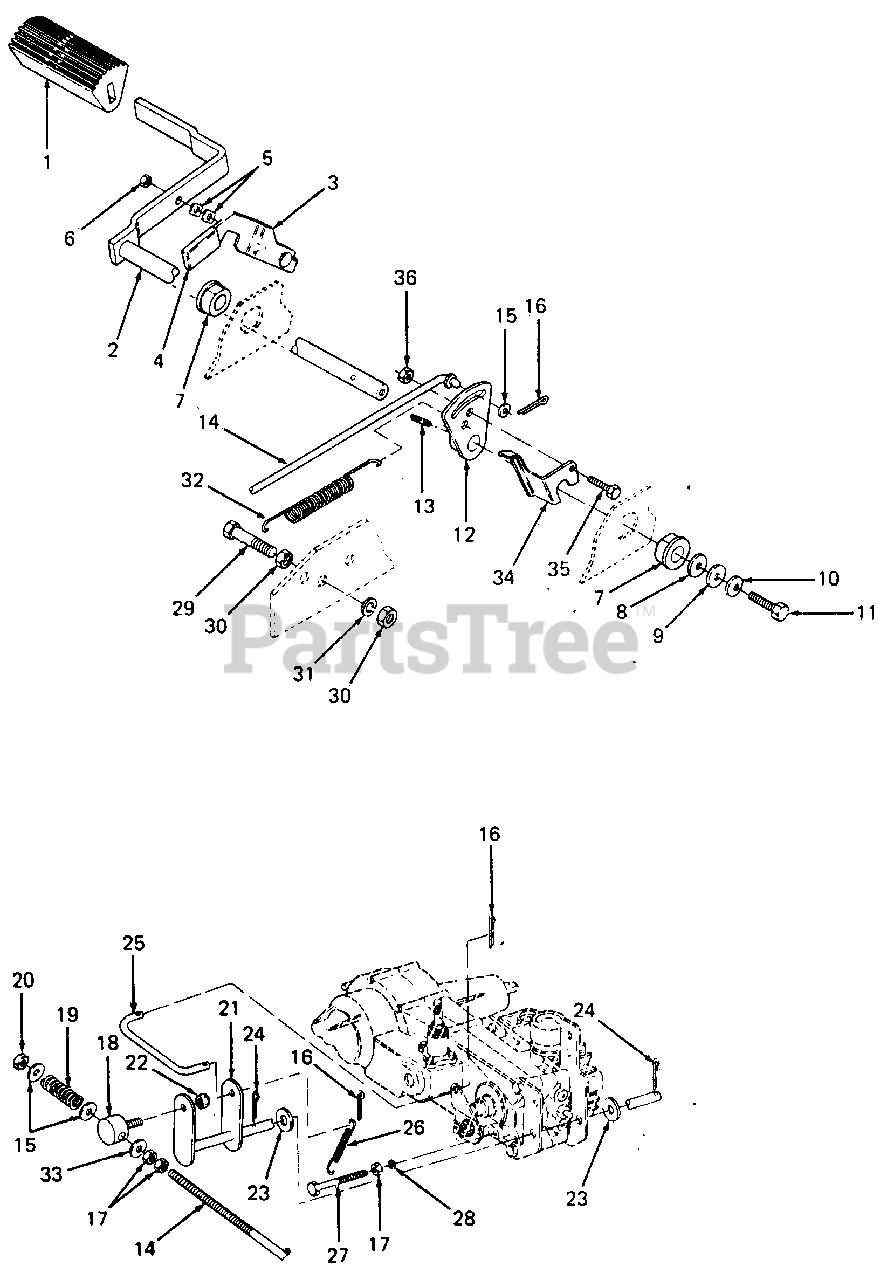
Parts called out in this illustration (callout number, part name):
1	Pad, Foot
5	Washer, Wave
6	Nut, Hex Insert Lock, 1/4-20
7	Bearing, Flange
8	Washer, Flat, .635 X 1.12 X .090 Thk
9	Washer, Flat, .26 X .93 X .120 Thk
10	Washer, Bell, .265 X .75 X .062 Thk
11	Screw, Hex Cap, 1/4-20 X .75 Lg GR5
12	Cam, Brake
13	Pin, Spiral Spring, 3/16 Dia X 1.5 Lg
14	Rod, Brake
15	Washer, Flat, .281 X .73 X .063 Thk
16	Pin, Cotter, 3/32 X .75 Lg
17	Nut, Hex Jam, 1/4-20
19	Spring, Compression, .58 OD X 2.00 Lg
20	Nut, Hex Center Lock, 1/4-20
21	Shaft, Brake
22	Nut, Hex Insert Lock, 5/16-18
23	Washer, Flat, .510 X 1.0 X .060 Thk
24	Pin, Cotter, 1/8 Dia X 1.0 Lg
25	Link, Brake
26	Spring, Extension
27	Screw, Hex Patch, 1/4-20 X 1.5 Lg GR5
28	Washer, Lock, 1/4
29	Screw, Hex Cap, 3/8-16 X 3.0 Lg
30	Nut, Hex, 3/8-16 GR5
31	Washer, Lock, 3/8
32	Spring, Extension, .50 OD X 3.97 Lg
33	Washer, Flat, .281 X .50 OD X .063 Thk
36	Nut, Hex Patch Lock, 1/4-20
